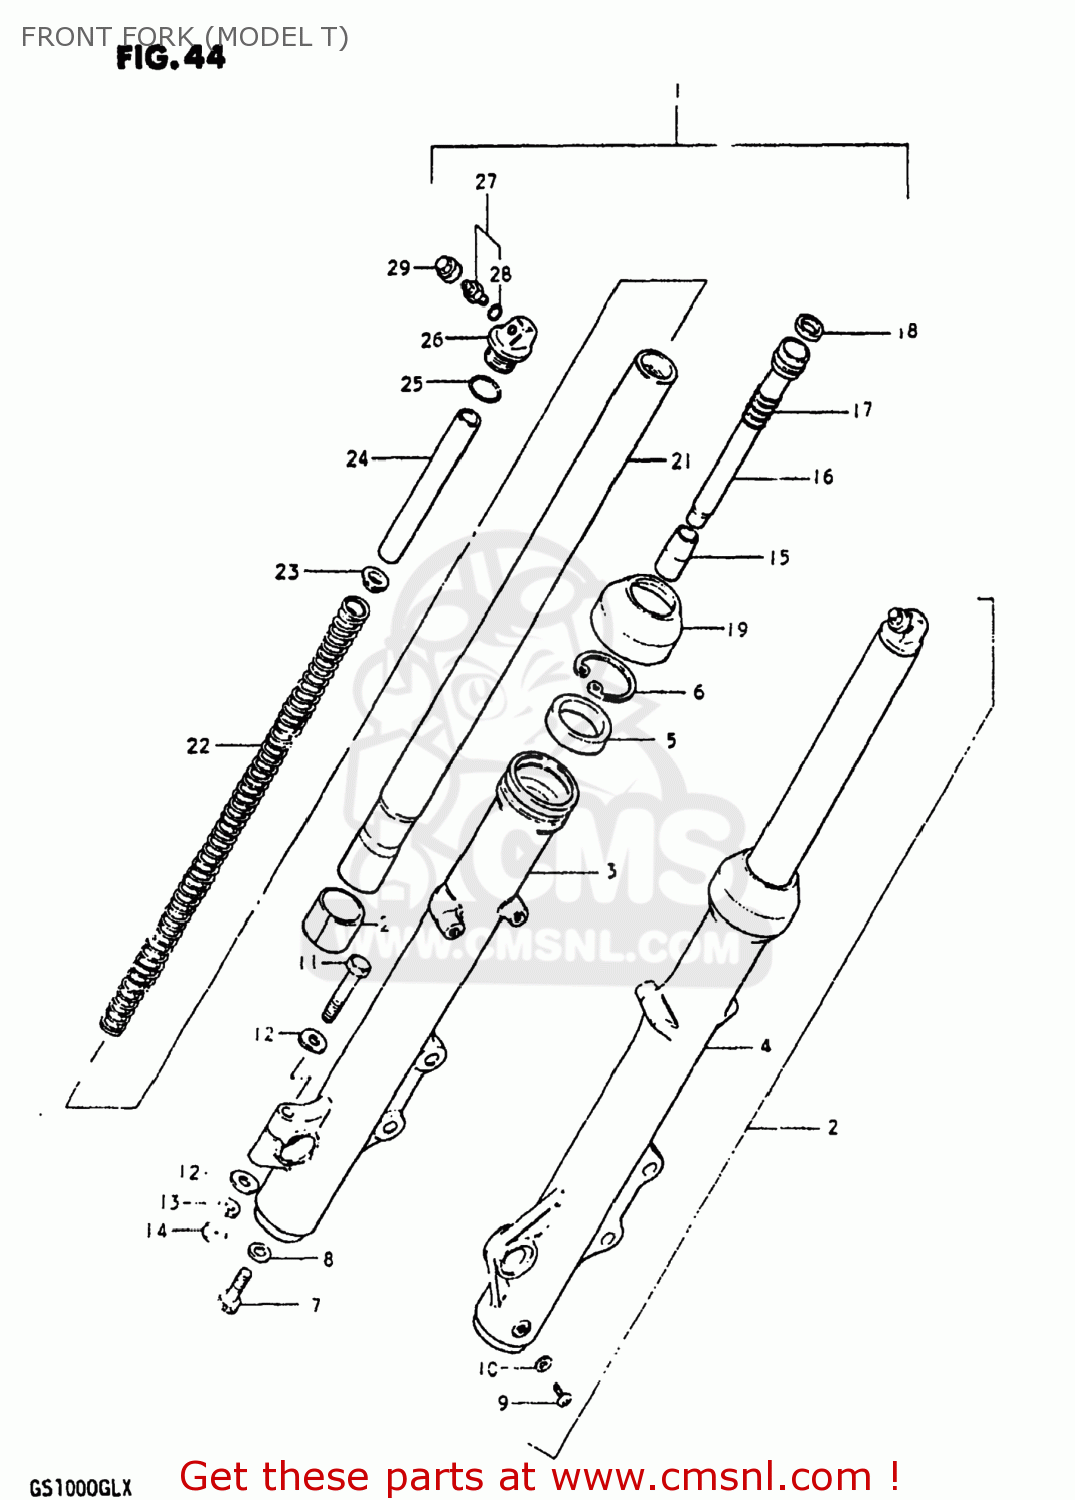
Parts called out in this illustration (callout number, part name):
1	DAMPER ASSEMBLY,RIGHT
2	DAMPER SET
3	TUBE,FORK,OUTER,RIGHT
4	TUBE,OUTER,LEFT
5	OIL SEAL,FRONT FORK
6	RING,STOPPER
7	BOLT,FORK CYLINDER(10X25)
8	GASKET (NAS)
9	SCREW
10	GASKET,DRAIN,PLUG (NAS)
11	BOLT 8X50
12	WASHER
13	WASHER,LOCK,8.
14	NUT
15	PIECE,OIL LOCK
16	CYLINDER,FRONT FORK
17	SPRING,REBOUND
18	RING,PISTON
19	SEAL,DUST
20	PISTON
21	TUBE,FORK,INNER
22	SPRING,FRONT FORK
23	GUIDE,FRONT FORK SPRING C
24	COLLAR,SPRING
25	O RING
26	CAP
27	VALVE
28	O RING
29	CAP,VALVE
